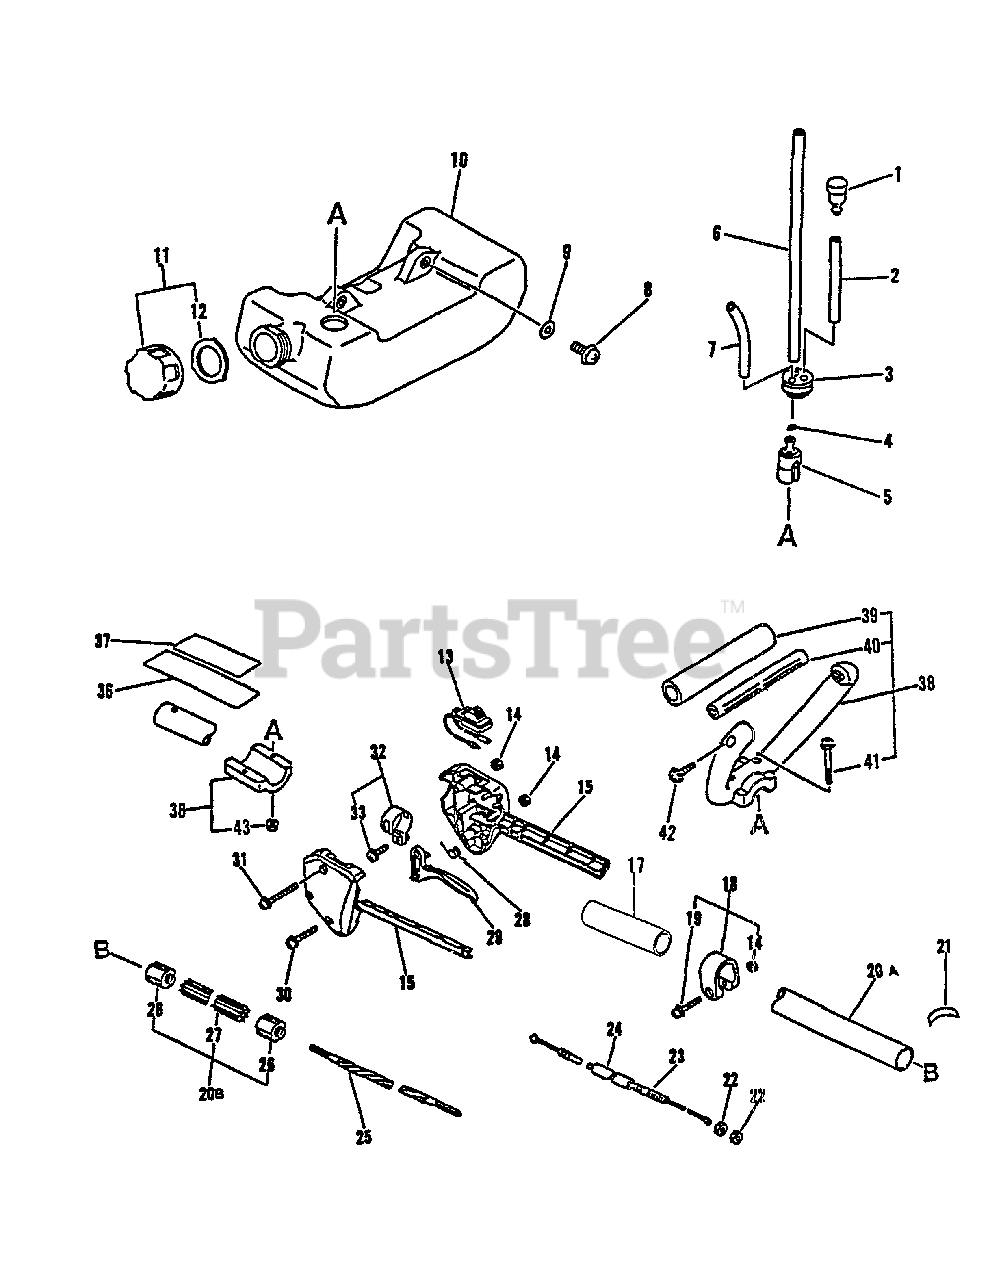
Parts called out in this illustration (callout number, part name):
1	VENT ASSY
2	PIPE, FUEL 3x-5x-70 BLACK
3	GROMMET, FUEL
4	CLIP 6 MM
5	FILTER, FUEL
6	PIPE, FUEL 3x-5x-180
7	PIPE, FUEL RETURN 3×6×90 MM CLEAR
8	SCREW 5×16
9	WASHER 5.5×12×0.8
10	TANK, FUEL
11	CAP ASSY
12	GASKET, FUEL CAP
13	IGNITION SWITCH ASSY
14	NUT M5
15	HANDLE KIT, CONTROL
17	GRIP, HANDLE
18	CLAMP KIT
19	SCREW 5×28
20	MAIN PIPE ASSY 25×1500
20A	MAIN PIPE ASSY 25×1500
20B	MAIN PIPE ASSY 25×1500
21	LABEL - ALIGNMENT
23	CABLE, THROTTLE
25	DRIVESHAFT - FLEXIBLE L= 1522
27	LINER, FLEXIBLE 21.6×1420
28	SPRING, TORSION
29	TRIGGER, THROTTLE
30	SCREW 5×25
31	SCREW 5×35
32	CLAMP KIT
33	SCREW 5×14
34	SCREW 5×40
35	WASHER, FLAT 5.5×10×0.8
36	LABEL - CAUTION
37	LABEL, CAUTION
38	LOOP HANDLE ASSY
39	GRIP, HANDLE
41	SCREW 6×25
42	SCREW 5×30
43	NUT, HEX M6
